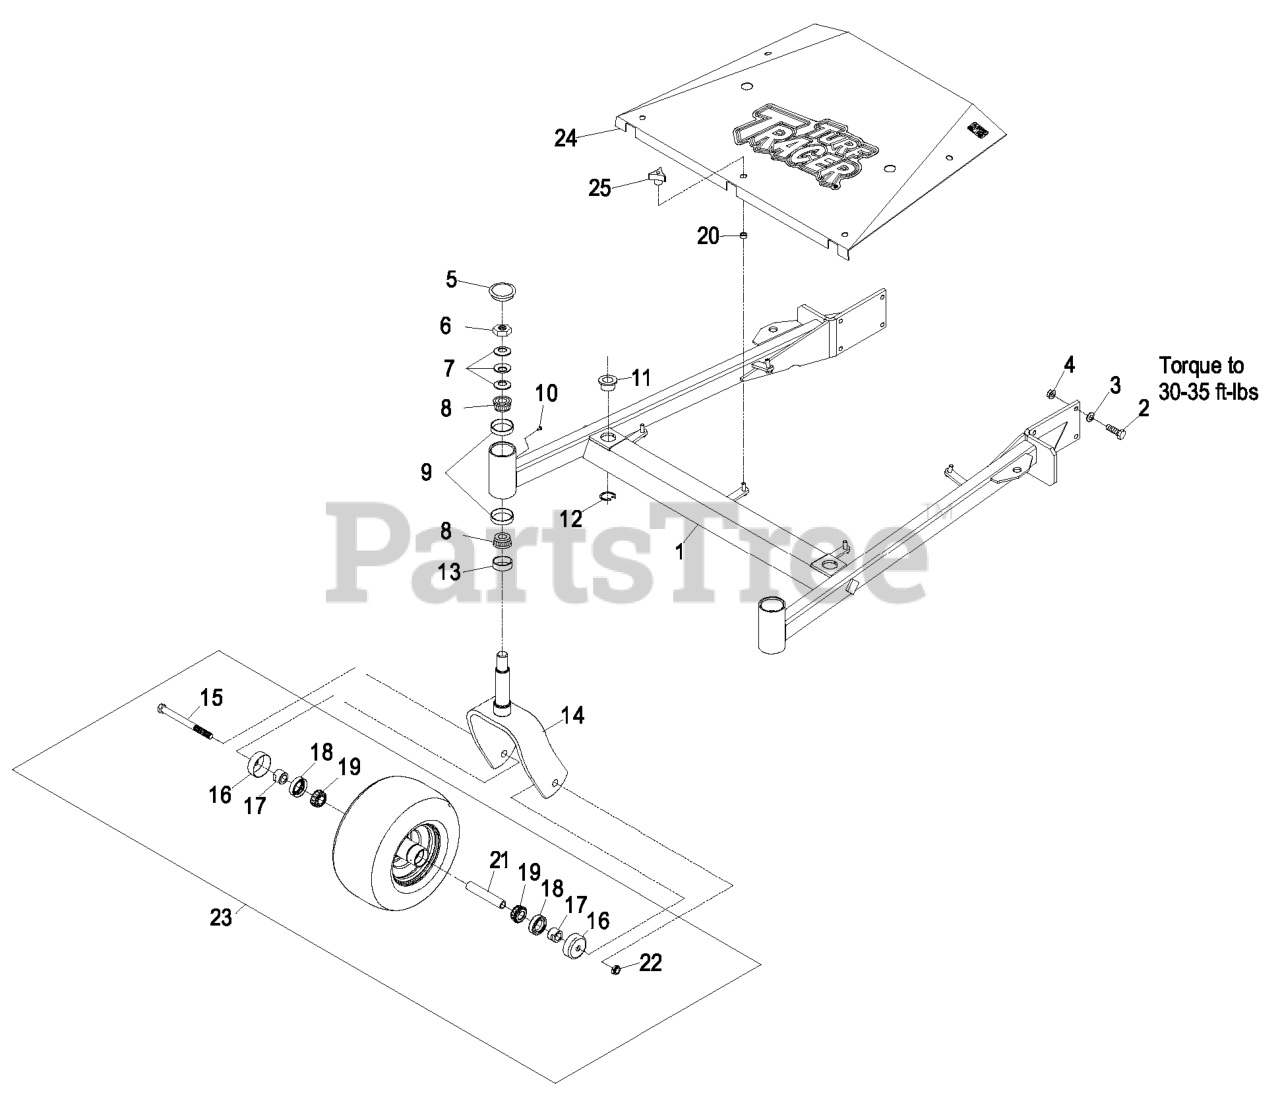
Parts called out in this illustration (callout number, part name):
1	ASM,524 FMD DK SUPPORT,SE
2	SCREW-HH
3	WASHER-BELLEVILLE
4	NUT-HHF, WHIZ
5	CAP-GREASE
6	NUT-LOCK, NI
7	WASHER-BELLVILLE
8	Cone-Bearing Tapered Roller
9	CUP-BEARING
11	BUSHING-DECK
12	RING-RETAINING
13	SEAL-GREASE
14	WLD, CASTER FORK
15	SCREW-HH
16	GUARD-SEAL
17	SPACER-NUT
18	SEAL-CASTER
19	BEARING-CONE, TAPERED ROLLER
22	NUT-HEX
23	ASM,WHEEL&BEARINGS
24	KIT, SHIELD TT W/ DECALS
25	KNOB-3 PRONG
